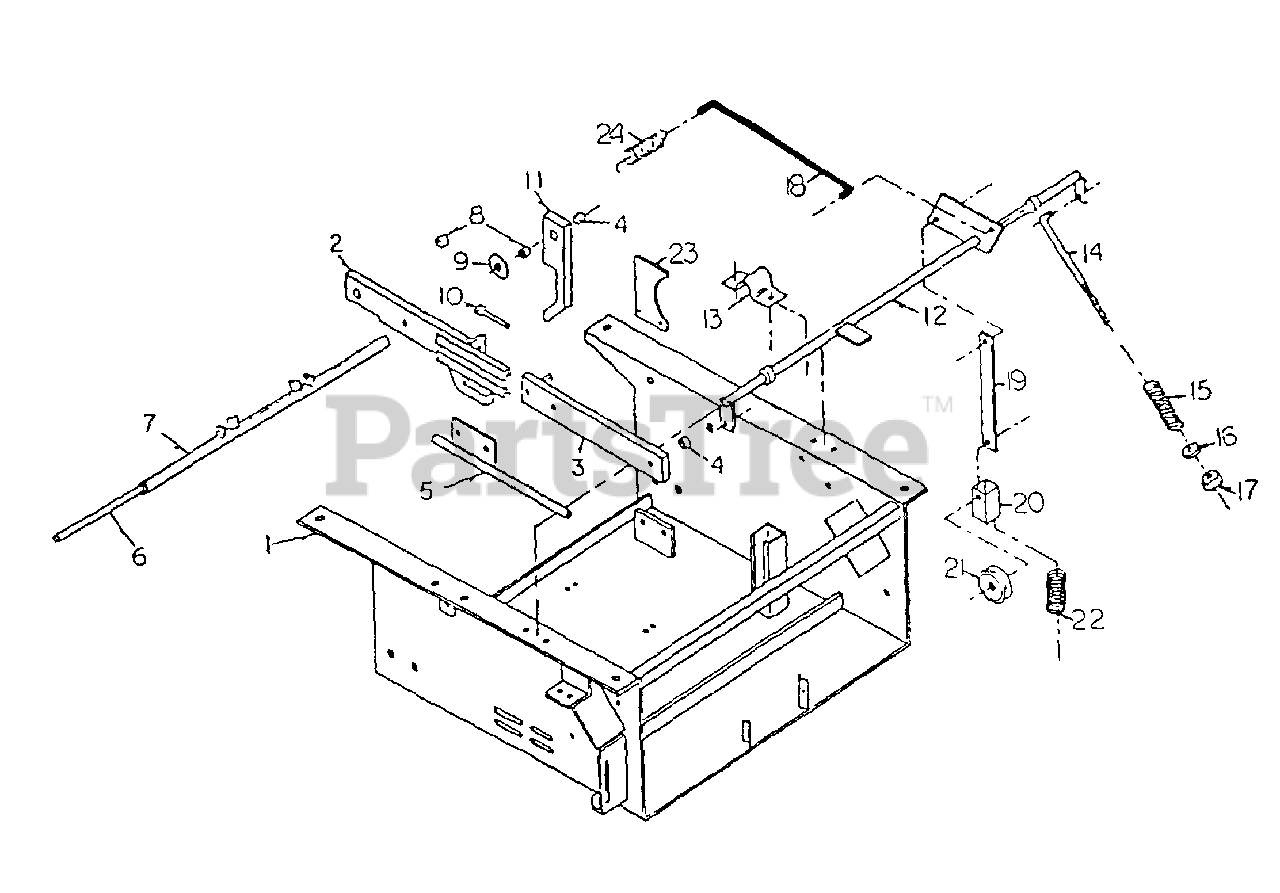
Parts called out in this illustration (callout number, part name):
1	Base
2	Deck Lift Arm, Front R.H.
3	Deck Lift Arm, Back R.H.
4	Bushing, Short
6	Cross Bar Pin
8	Bushing, Long
9	Body Mount Washer
10	Tap Bolt, 3/8-16 x 3", GR5
11	Forward Nose Down Lock
12	Brake Clutch Cross Rod
13	Bearing, Brake Cross Rod
15	Caliper Spring
16	Flatwasher, 1/4"
17	Elastic Stop Nut, 1/4-20
18	Brake Pedal Rod
19	Cross Rod to Idler Pulley
20	Spring Loaded Idler Mount
21	Idler Pulley
24	Brake Pedal Spring
